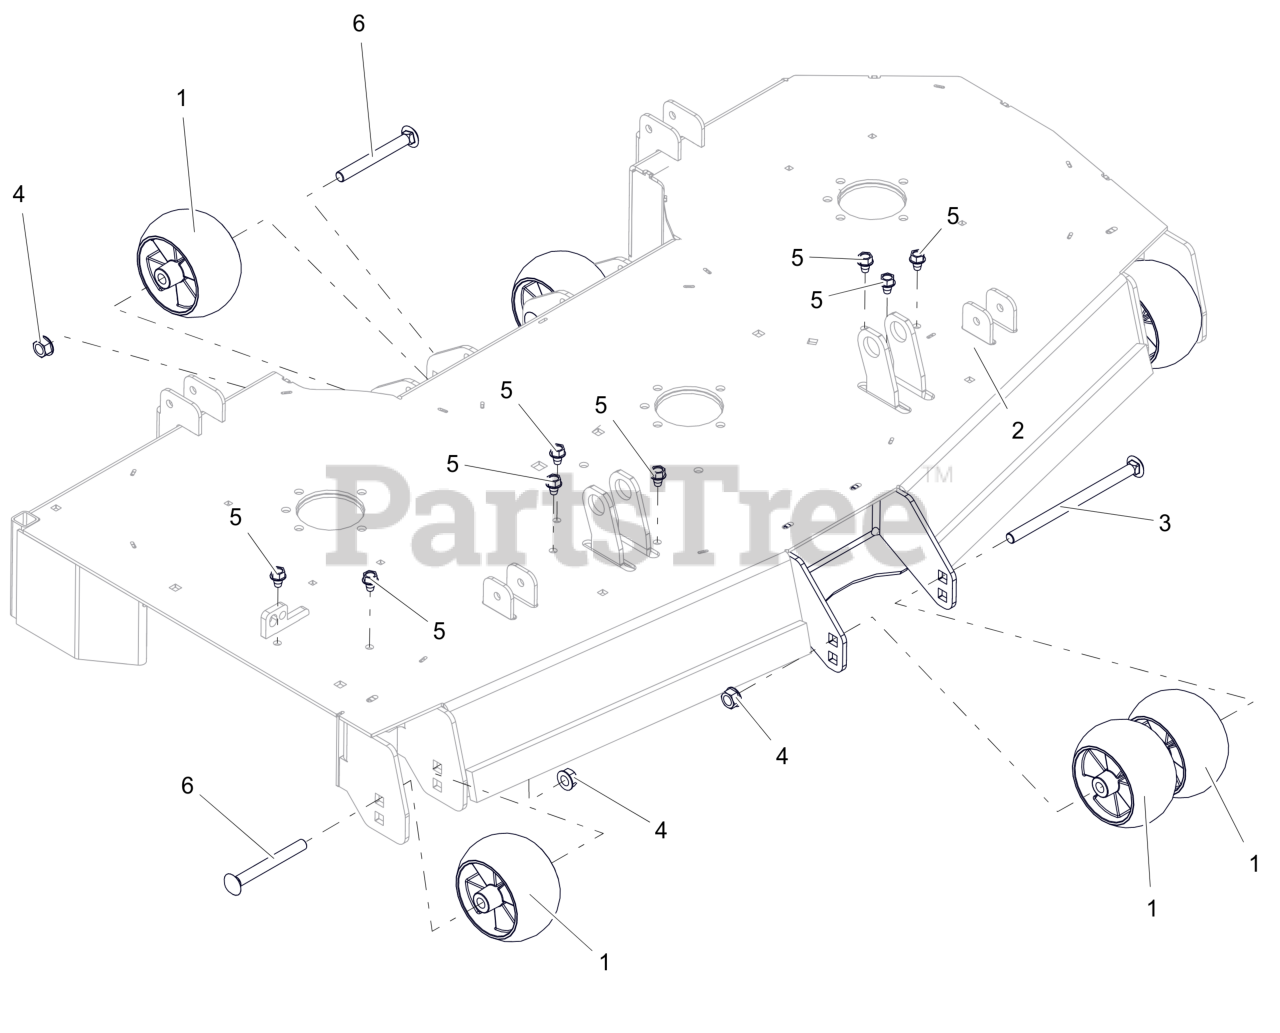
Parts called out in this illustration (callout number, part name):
1	WHEEL, ANTI SCALP - 5X3 CTR W/RIBS
2	BTL,RHSN .313-18 X 0.75 G5 ZCC LT
3	BLT,RHSN .50-13X8.00 G5 ZCC NS
4	NUT-LK-CTR-FLG .500-13 GG ZCC
5	SCR,TAP .375-16X.50 HWH TR ZCC
6	BLT,RHNS .50-13X4.50 G5 ZCC NS
